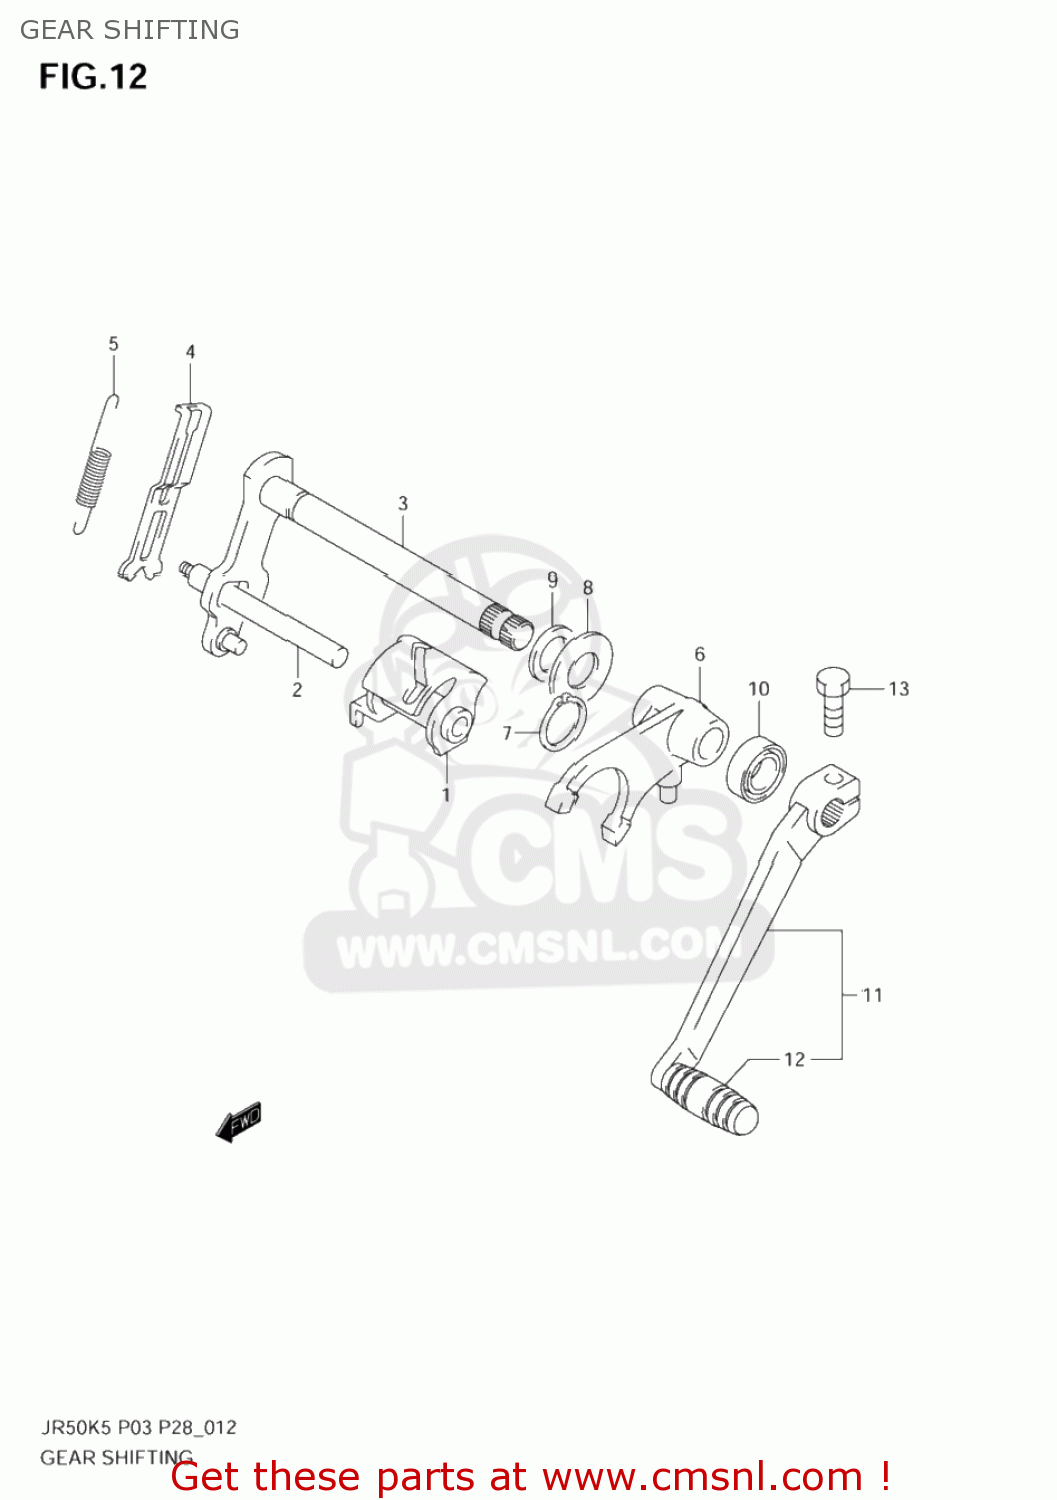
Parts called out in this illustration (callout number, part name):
1	CAM,GEAR SHIFT
2	SHAFT,GEAR SHIFT CAM
3	SHAFT,GEAR SHIFT
4	ARM,GEAR SHIFT CAM STOPPER
5	SPRING
6	FORK,GEAR SHIFT
7	CIRCLIP,12 MM
8	WASHER
9	WASHER
10	OIL SEAL
11	LEVER ASSY,GEAR SHIFT
12	RUBBER,GEAR SHIFT PEDAL
13	BOLT
